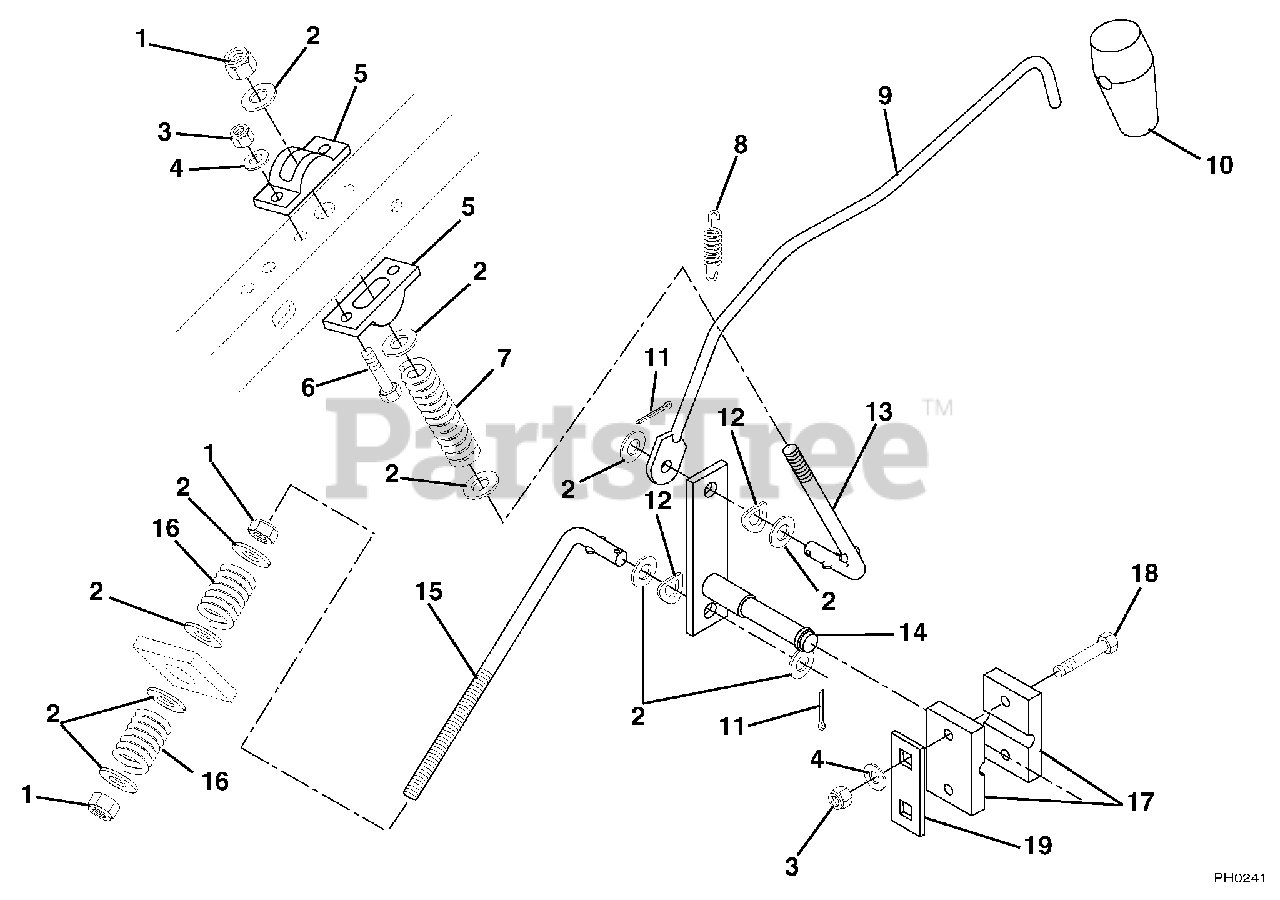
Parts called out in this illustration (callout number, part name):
1	Nut-Locking-Center .375-16 Grade 2
2	Washer-Flat-Steel .406 x .812 x .065
3	Nut-Locking-Center .250-20 Grade 2
4	Washer-Flat-Steel .281 x .620 x .065
5	Cam-Shifter
6	Bolt-Hex .25-20 x 1.00 Grade 5
7	Spring-Compression .081 x .720 x 2.75
8	Spring-Tension .041 x 1.25 x .50
9	Rod-Shifter
10	Handle-Rubber Shifter
11	Pin-Cotter .12 x .75
12	Spring Washer
13	Link-Shifter Stop
14	Weldment-Shifter Crank
15	Link-Shifter
16	Spring-Compression .125 x .78 x 1.00
17	Block-Shift Lever
18	Bolt-Hex .25-20 x 1.50 Grade 5
19	Shim-Mower Height Adjuster Bracket
